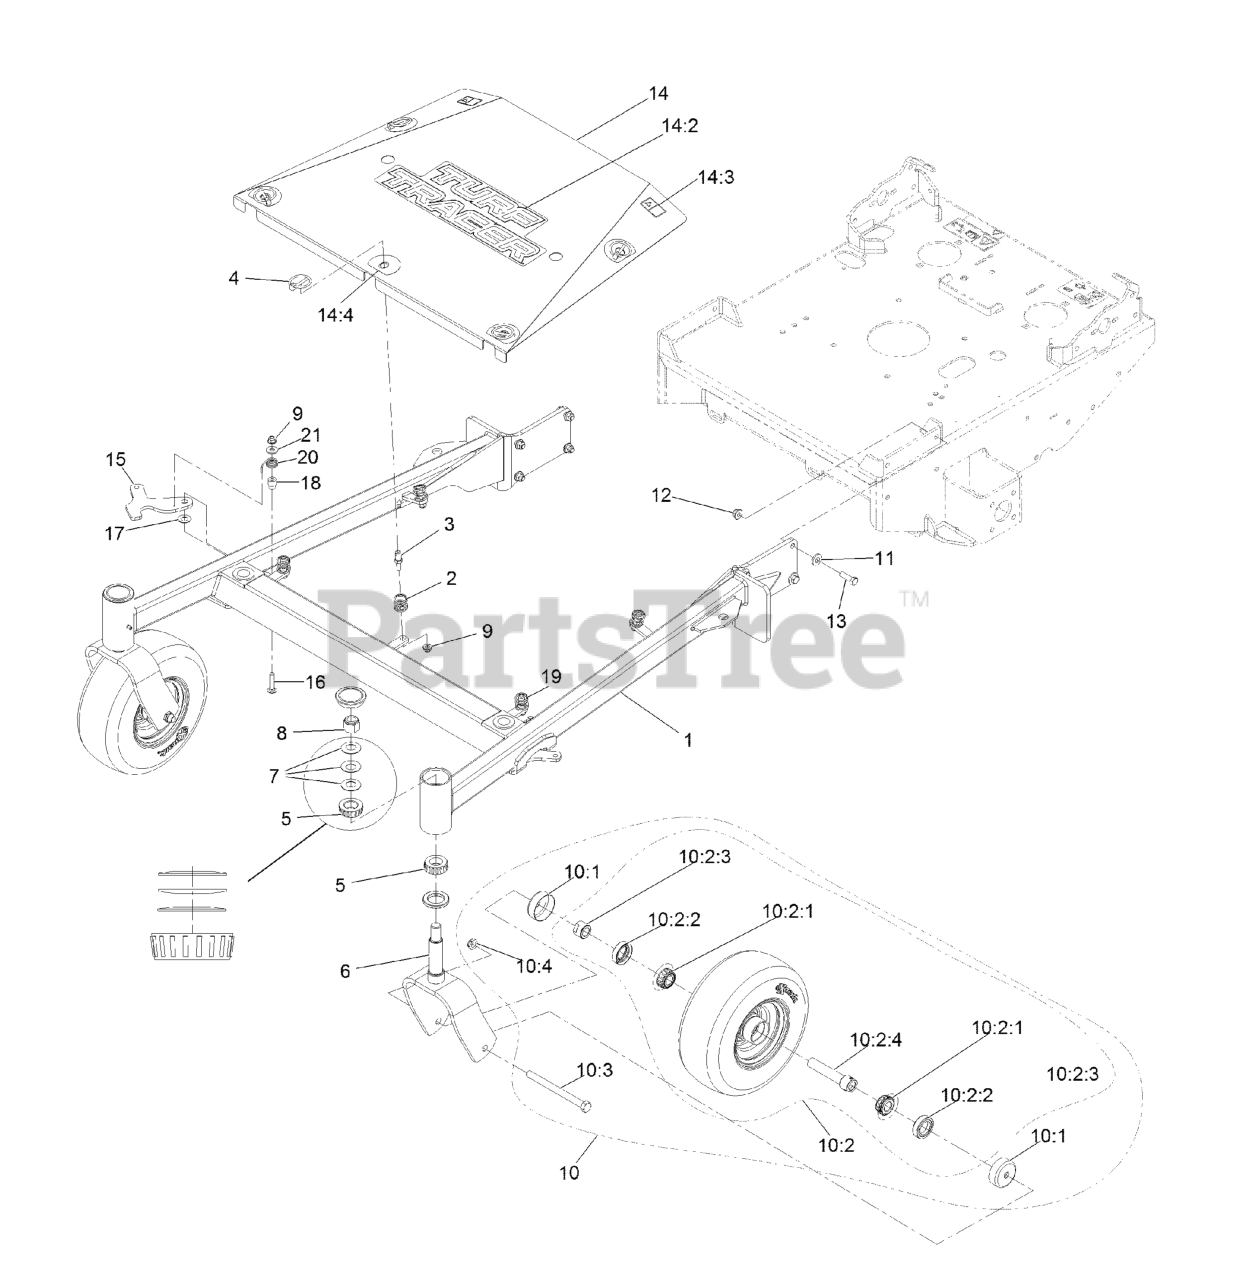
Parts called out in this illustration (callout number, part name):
1	ASM, FRONT FRAME W/ BEARI
3	PIN-SPRING
4	PIN-LYNCH
5	Cone-Bearing Tapered Roller
6	WLD, CASTER FORK
7	WASHER-BELLVILLE
8	NUT-LOCK, NI
9	NUT-HF, NI
10	ASM,WHEEL&BEARINGS
10:1	GUARD-SEAL
10:2	Wheel And Bearing ASM
10:2:1	BEARING-CONE, TAPERED ROLLER
10:2:2	SEAL-CASTER
10:2:3	SPACER-NUT
10:2:4	CASTER AXLE ASM
10:3	SCREW-HH
10:4	NUT-HEX
11	WASHER-BELLEVILLE
12	NUT-HF, NI
13	SCREW-HH
14	ASM, CENTER SHIELD W/ DEC
14:2	DECAL-TURF TRACER
14:3	DECAL-WARNING
14:4	DECAL-SCRATCH COVER
15	LATCH, DECK HEIGHT
16	BOLT-CARR
17	Washer-Plastic
18	Collar-Basket
19	Spring-Torsion, LH (Yellow)
20	Spring-Torsion, RH
21	WASHER-FLAT
